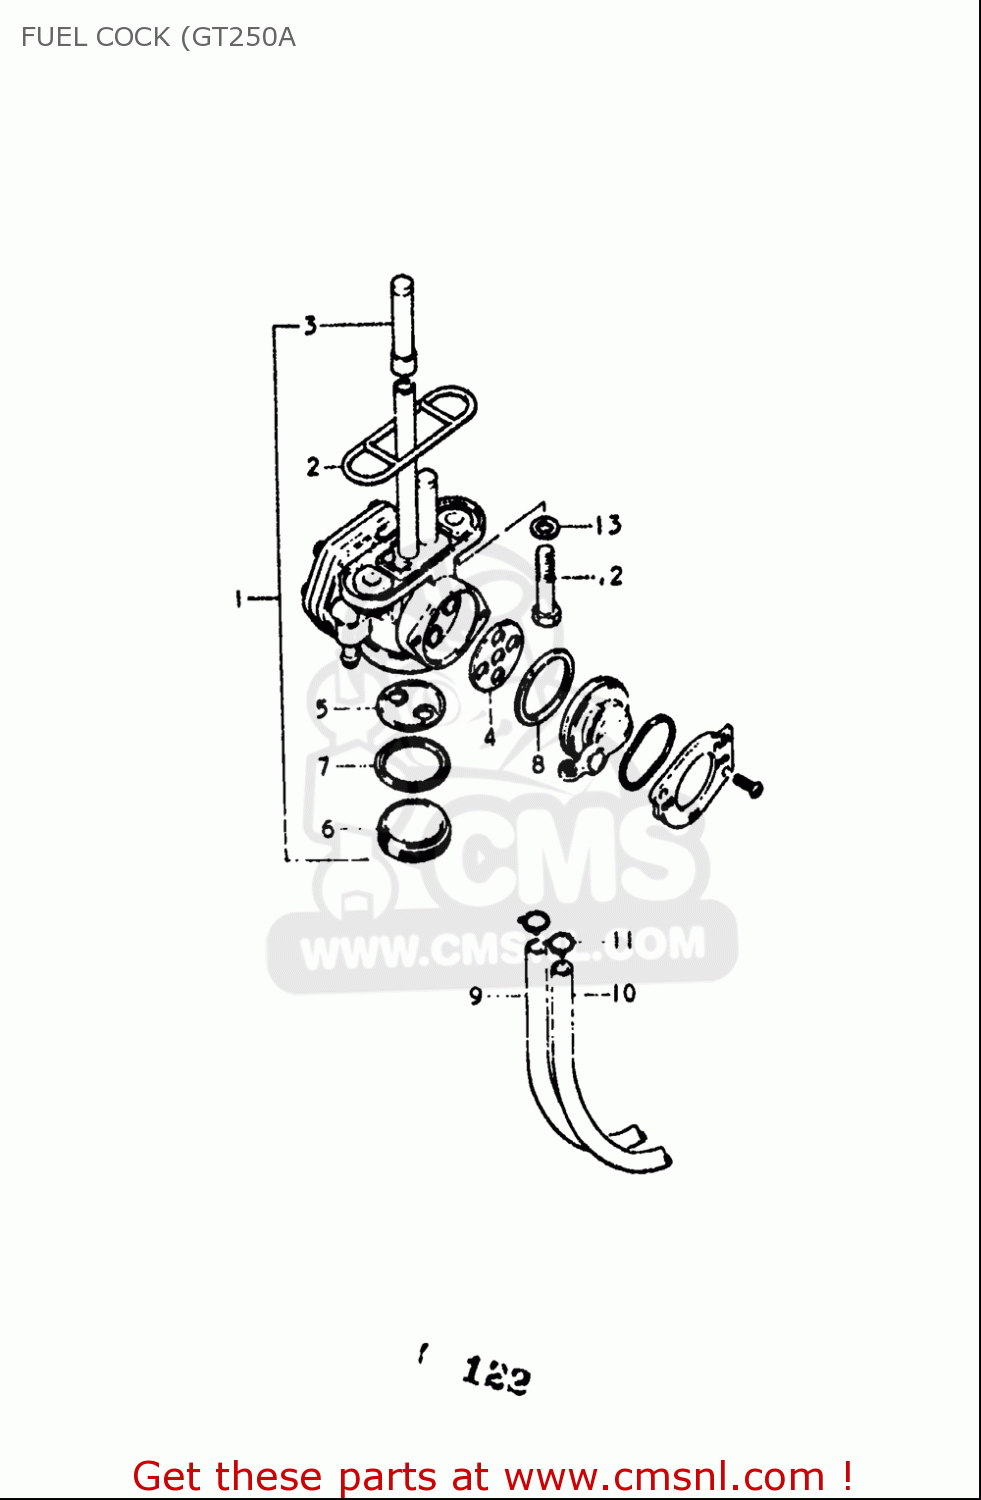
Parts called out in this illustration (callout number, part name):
2	GASKET, FUEL COCK (NAS)
3	FILTER
4	GASKET (NAS)
5	FILTER,CUP
7	GASKET,CUP (NAS)
8	V SEAL,FUEL COCK
9	HOSE(5X9X600)
10	HOSE(5X8.2X600)
11	CLIP
12	BOLT(6X20)
13	GASKET(5.8X13X1.2) (NAS)
